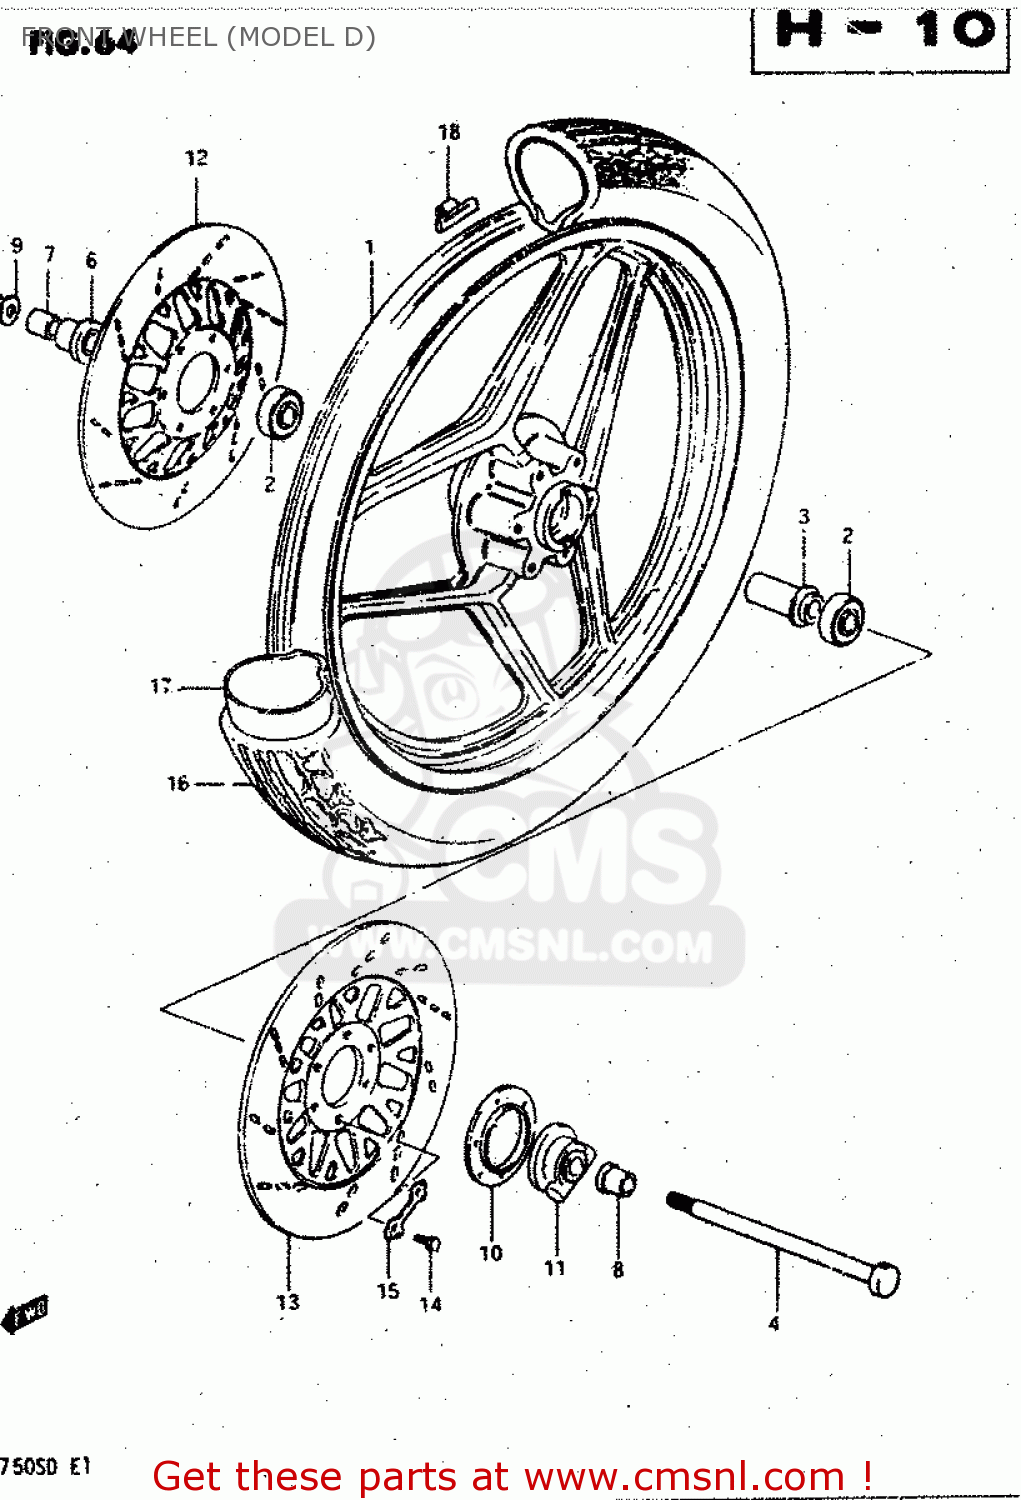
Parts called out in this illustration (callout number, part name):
1	CASTING WHEEL,FRONT 1.85
2	BEARING
3	SPACER,FR HUB BEARING
4	AXLE,FR
5	NUT
6	SPACER,FR AXLE,R
7	SPACER,FR AXLE,R
8	SPACER,FR AXLE,L
9	WASHER
10	DUST SEAL,SPEEDOMETER GEAR BOX
11	BOX ASSEMBLY,SPEEDOMETER GEAR
12	DISC,FR BRAKE,R
13	DISC,FR BRAKE,L
14	BOLT(8X25)
15	WASHER
16	TIRE,FRONT
17	TUBE,INNER
18	BALANCER,WHEEL
